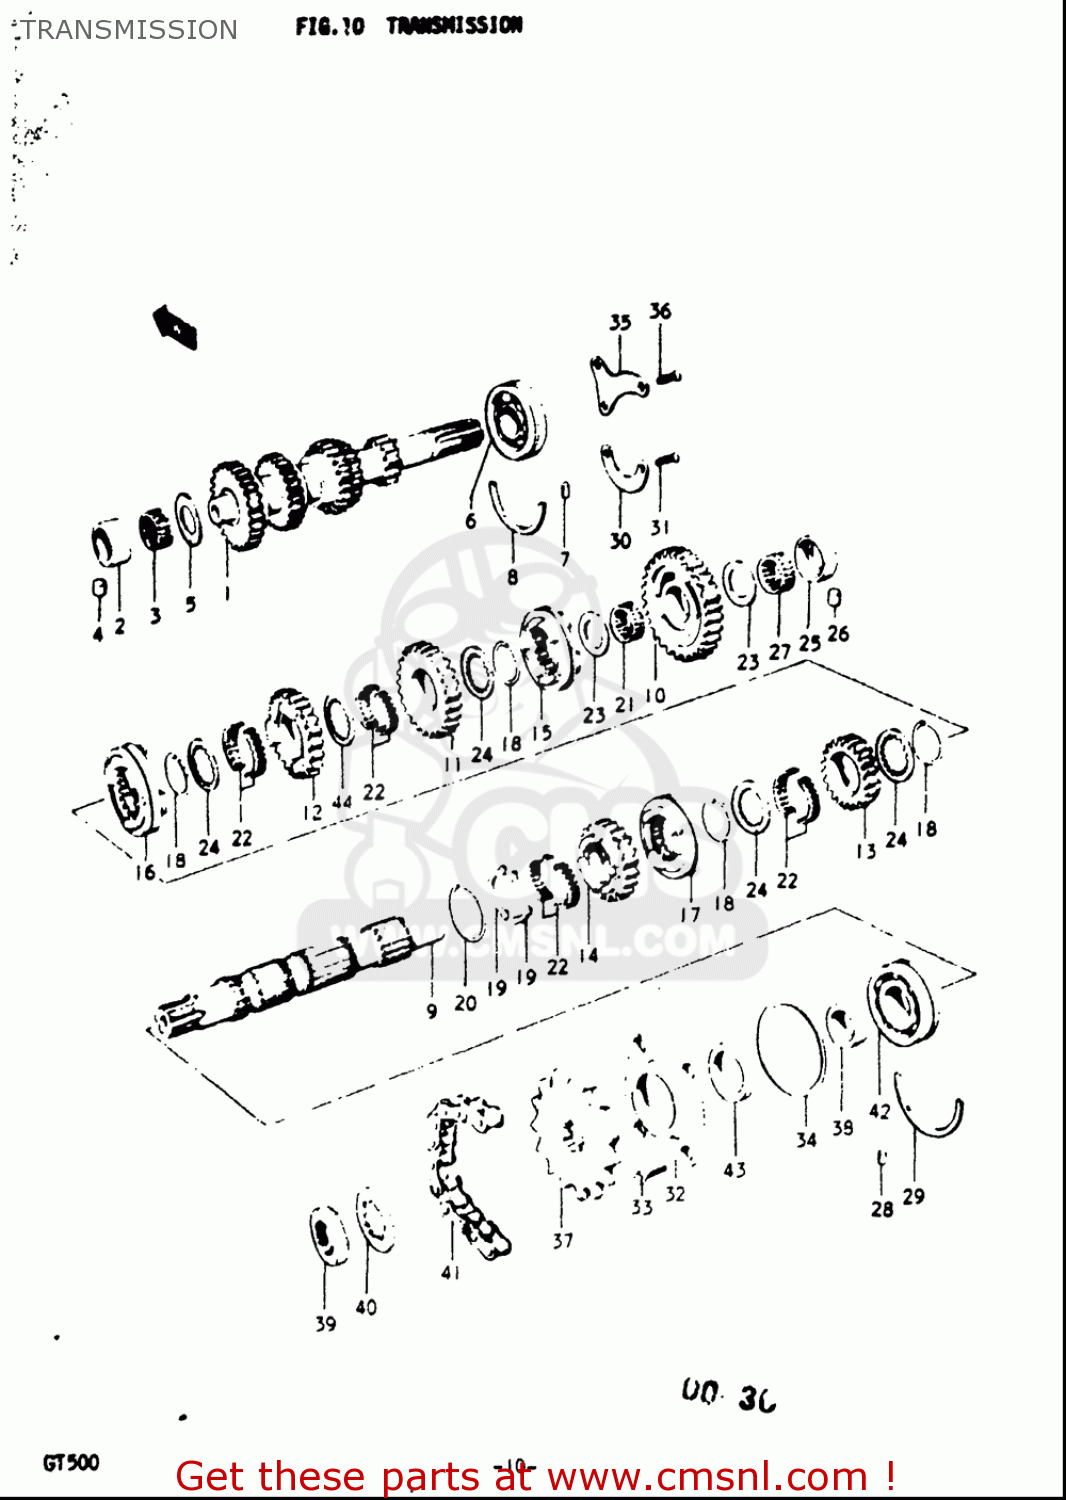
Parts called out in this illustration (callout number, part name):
2	BUSHING
4	PIN
5	WASHER (20X30X1)
7	PIN
8	C-RING
12	GEAR,THIRD DRIVEN
18	SPRING
19	KNOCK RING
22	ROLLER BEARING (NTN
23	WASHER (20X30X1)
24	WASHER,LOCK
25	BUSHING
26	PIN
28	PIN
29	C-RING
31	SCREW
33	SCREW
34	O RING(D:1.9,ID:63.1)
36	SCREW
37	SPROCKET,ENGINE
38	SPACER (22X27X10.6)
39	NUT
40	WASHER,LOCK
42	BALL BEARING 22X59X.6
43	SEAL,OIL(25.9X42X7)
44	WASHER
